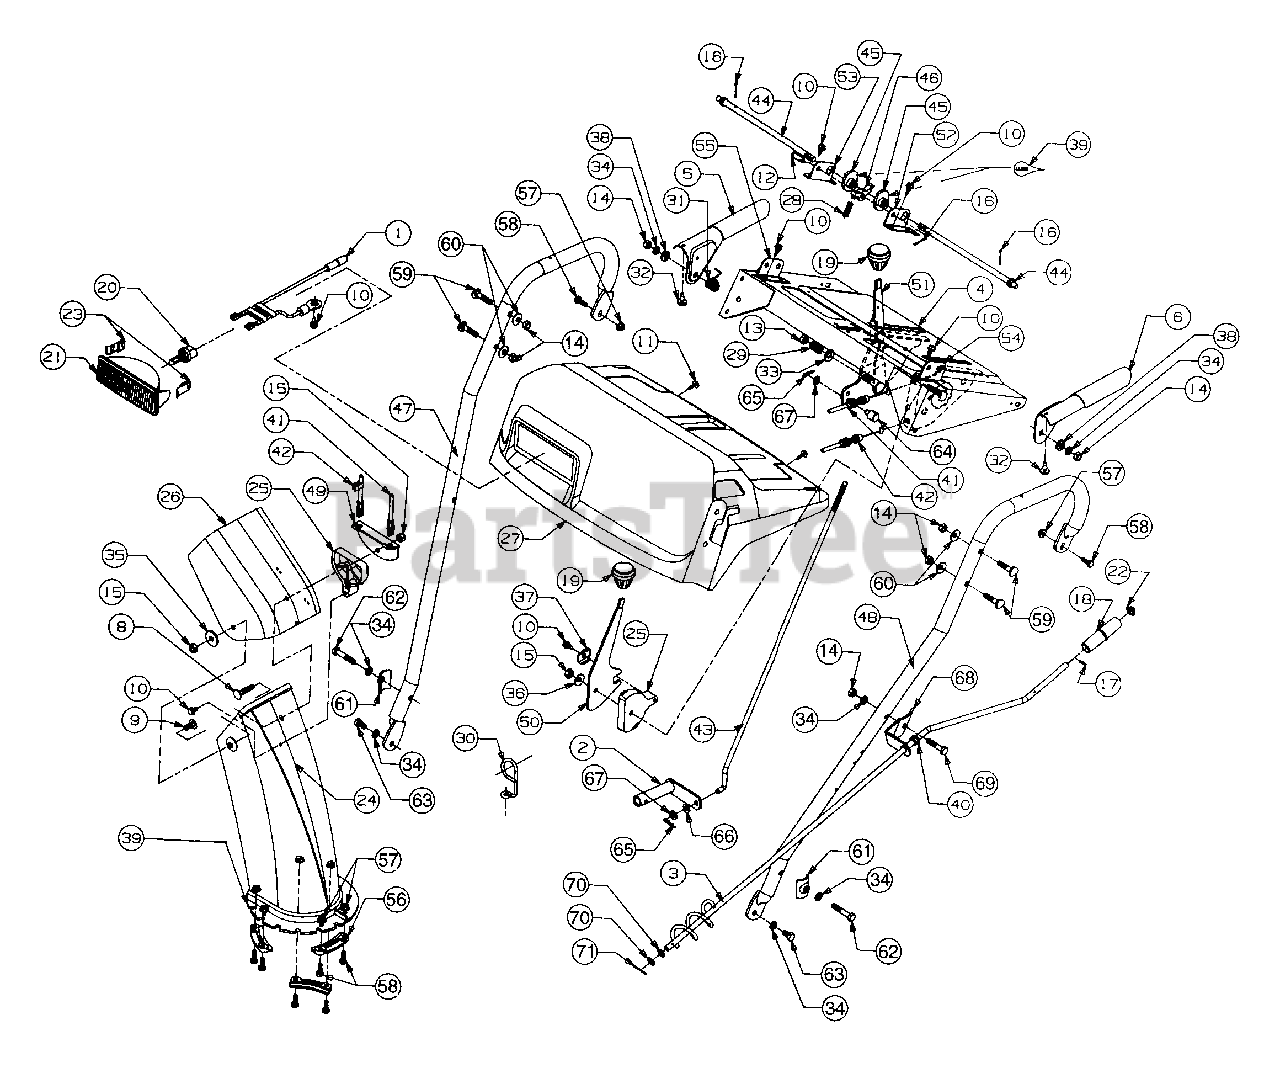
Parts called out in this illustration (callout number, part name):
1	Harness
2	Arm Shift
3	Crank Chute
6	Handle, Engagement - L.H.
8	Bolt - Carriage
9	Bolt - Carriage
10	Screw
12	Pin, Clevis
13	Nut, Hex Lock
14	Nut, Hex
15	Nut, Hex Lock
16	Pin, Cotter
17	Roll Pin
18	Knob, Chute Crank
19	Knob, Shift
20	Lamp, Halogen
21	Housing, Lamp, Lens
22	Cap, Push
23	Clip, Retaining
24	Lower Chute
25	Cable Guide
26	Chute, Upper
27	Panel Handle
28	Spring
29	Spring
30	Cable Control Wire
31	Spring
32	Bumper
33	Washer - Bell
34	Washer - Lock
35	Washer
36	Washer - Bell
37	Washer
38	Washer
39	Grease
40	Bushing, Plastic
41	Cable, Chute Control
42	Cable, Chute Deflector
43	Rod, Shift
44	Rod, Cam
45	Cam Handle Lock
46	Pawl Handle Lock
47	Handle - R.H.
48	Handle - L.H.
50	Handle - Shift Chute
51	Handle - Shift
52	Bracket, Handle Support - L.H.
53	Bracket, Handle Support - R.H.
55	Bracket, Handle Support - R.H.
56	Chute Flange Keepers
57	Hex L-Nut 1/4-20 Thd.
58	Hex Bolt 1/4-20 x 3/4" Lg.
59	Carr. Bolt 5/16-18 x 1.5" Lg.
60	Bell-Wash. 5/16" I.D.
61	Handle Tab
62	Hex Bolt 5/16-18 x 1.75" Lg.
63	Hex Bolt 5/16-18 x 5/8" Lg.
64	Ferrule
65	Hairpin Clip
66	Spr. Wash. 5/16" I.D.
67	Fl-Wash. 5/16" I.D.
70	Fl-Wash. 3/8" I.D.
71	Cotter Pin
